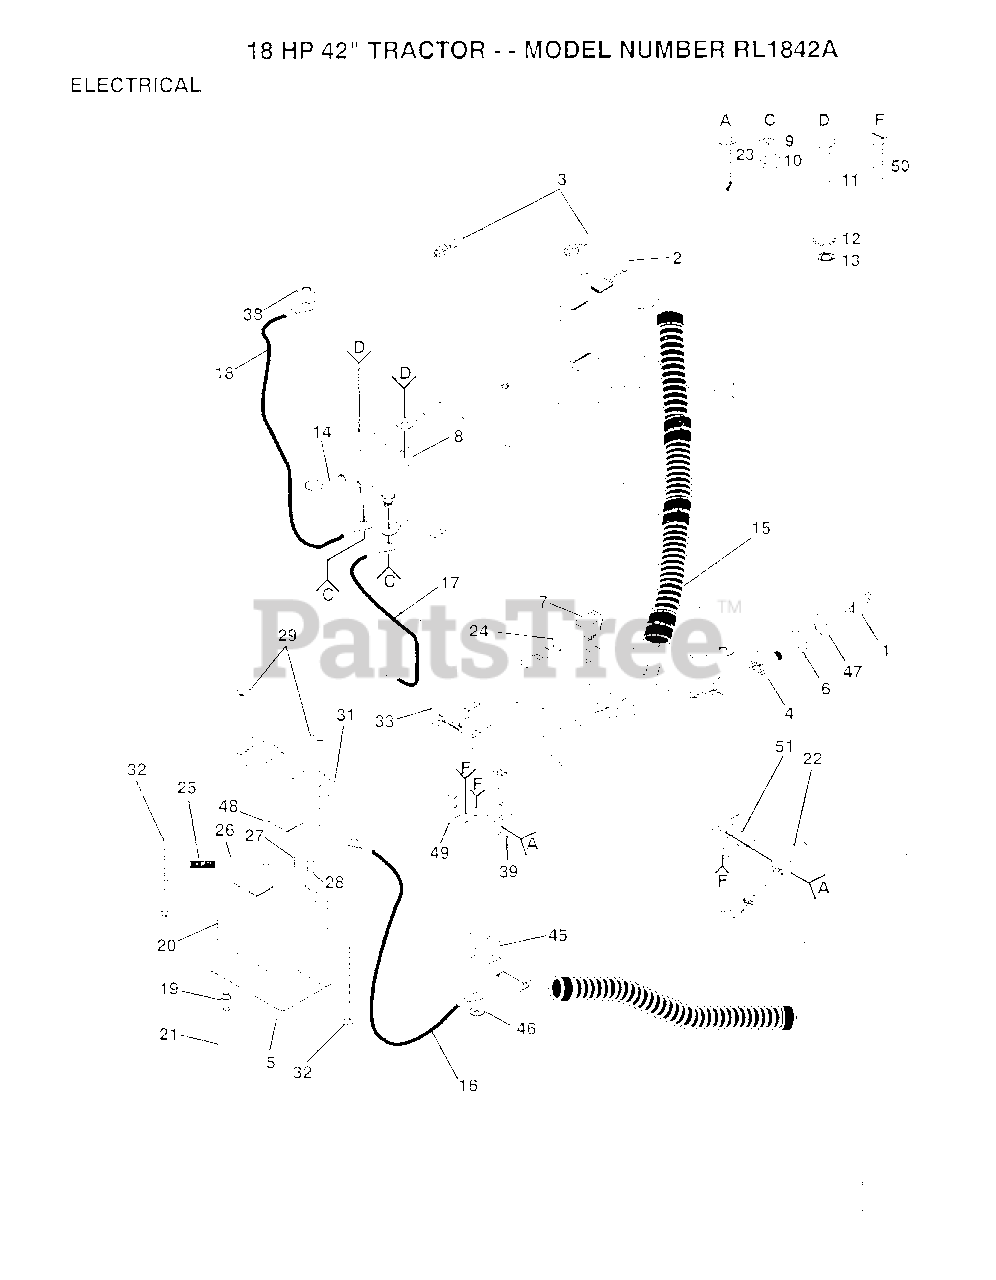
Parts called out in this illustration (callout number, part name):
1	KEY
2	"HARNESS,LIGHT SOC"
3	HEADLAMP BULB
5	"TRAY T, BATTERY"
6	NUT IGNITION
7	SWITCH LT
10	NUT
11	BOLT
13	NUT
15	HARNESS.IGN
16	"CABLE T, BATTERY"
17	CABLE LT
18	CABLE T
19	HOSE CLAMP T
21	"DRAIN TU T, BATT"
22	SWITCH-INTER. GT
23	SCREW
24	FUSE HYT
25	BOLT LT
26	WASHER
27	LOCKWASHER
32	BOLT
38	LOCKWASHER
39	SWITCH INTERLOCKT
45	SWITCH SEAT
46	LOCKWASHER
48	"CAP,BATTERY "
49	SWITCH BRACKET
50	SCREW
51	BRACKET LT
